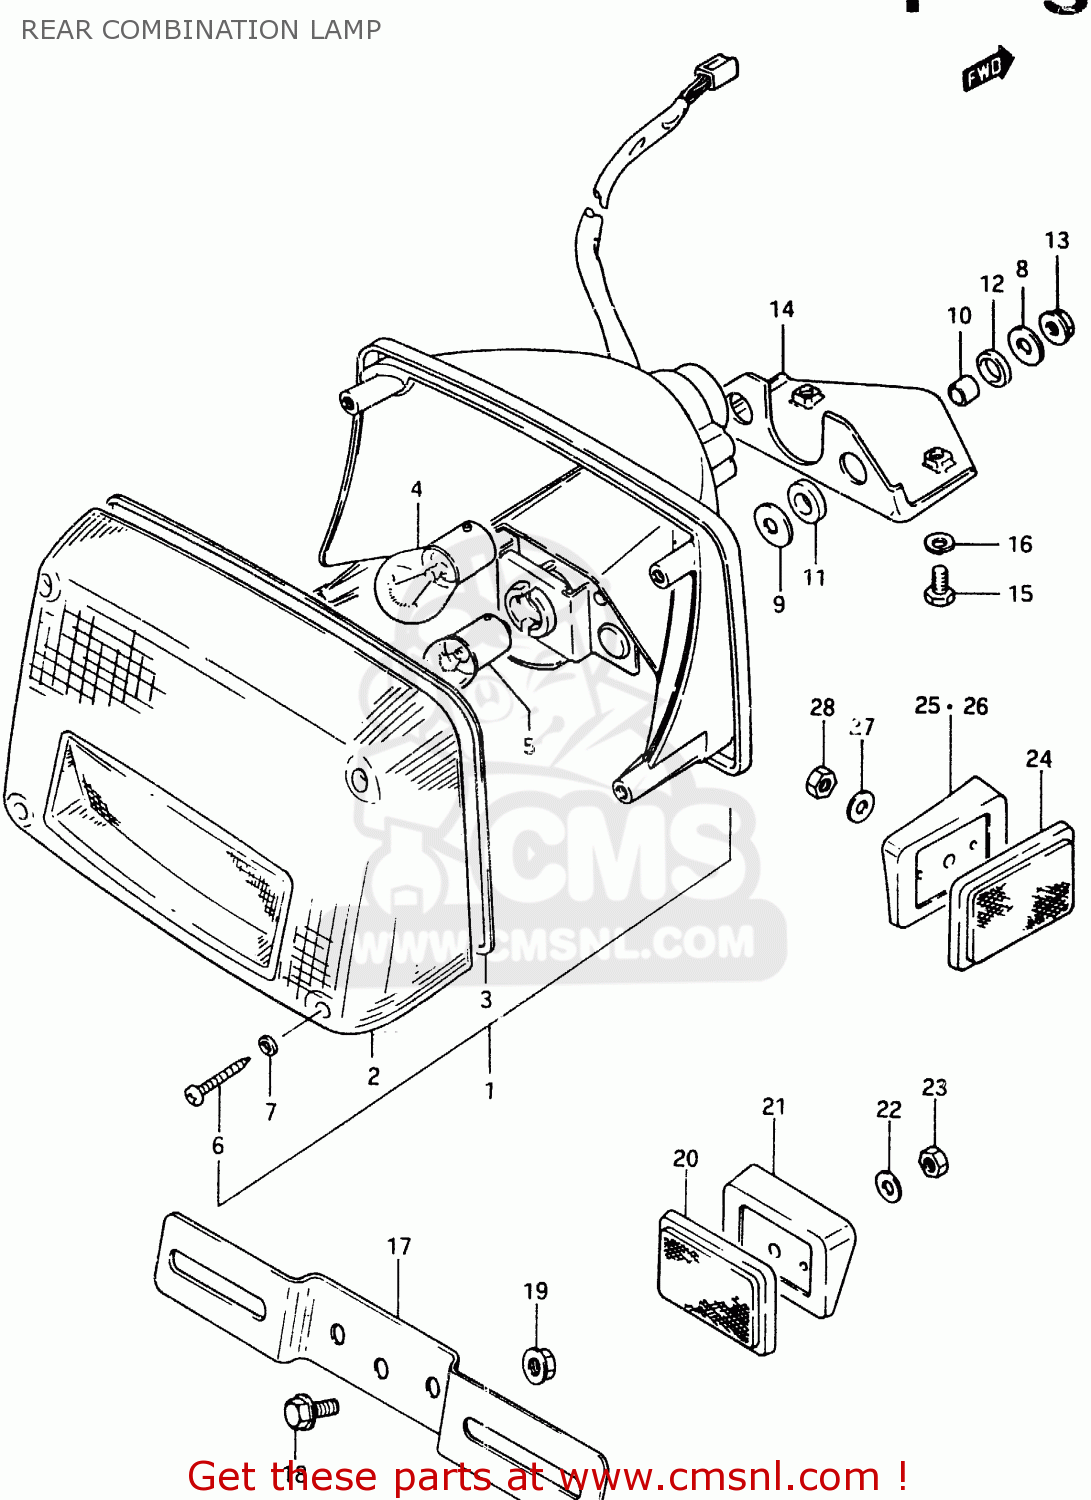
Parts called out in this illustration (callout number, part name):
1	LAMP ASSY,RR C
2	LENS
3	GASKET (NAS)
4	BULB(12V23W)
5	BULB
6	SCREW,REAR COMBINATION LAMP
7	GASKET (NAS)
8	WASHER
9	WASHER(6,5X22X1.6)
10	SPACER(6.1X9X7.5)
11	CUSHION
12	CUSHION
13	NUT
14	BRACKET,REAR COMBINATION LAMP
15	BOLT
16	WASHER,LOCK
17	PLATE,RR LICENSE
18	BOLT
19	NUT
20	REFLEX REFLECTOR,RR
21	SPACER
22	WASHER(5.2X16X1)
23	NUT
24	REFLECTOR,REFLEX
25	SPACER, RH
26	SPACER, LH
27	WASHER(5.2X16X1)
28	NUT
